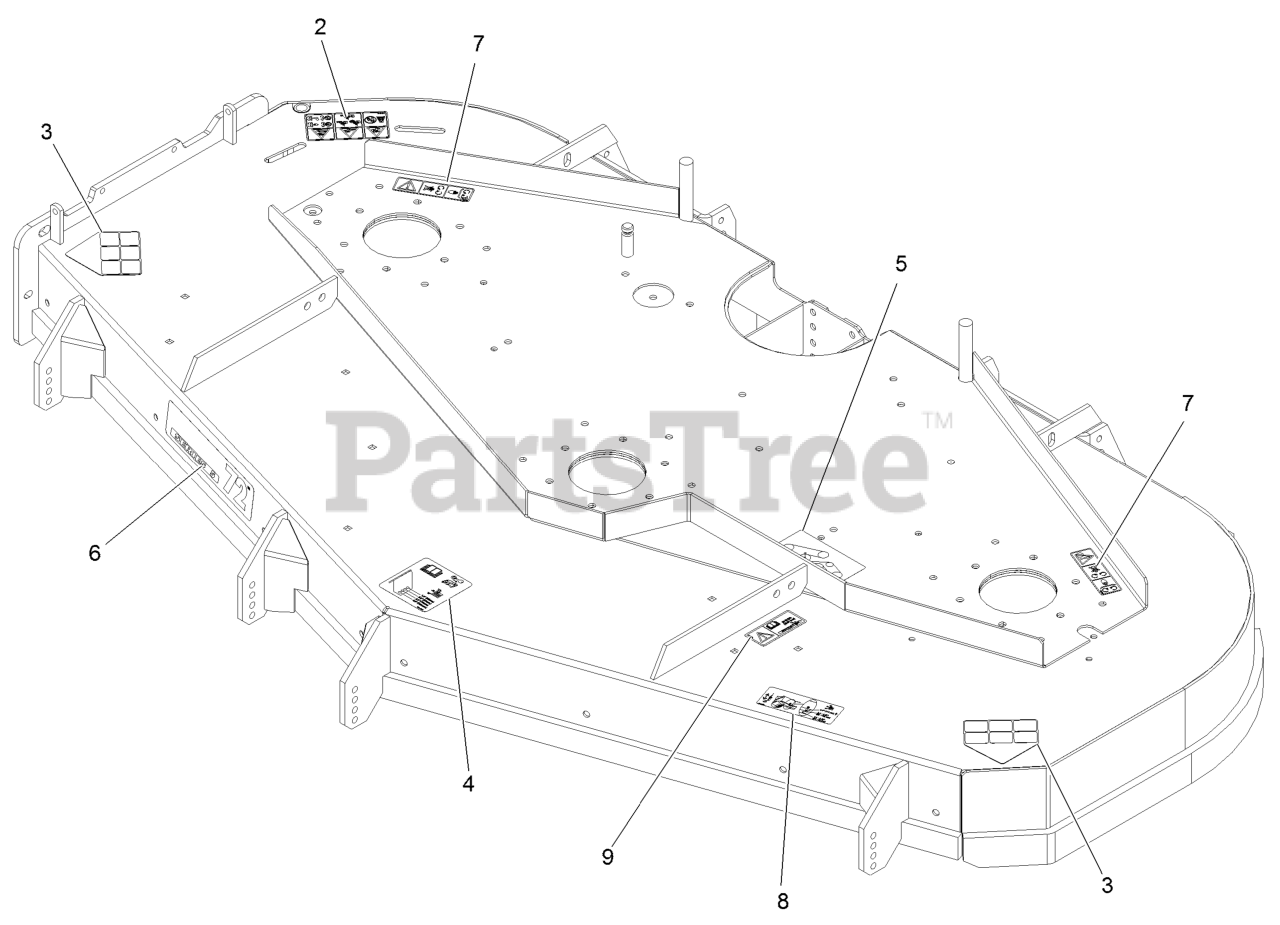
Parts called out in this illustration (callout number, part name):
2	DECAL-DANGER
3	DECAL-DANGER
4	DECAL-HEIGHT OF CUT
5	DECAL-BELT ROUTING
6	DECAL, SERIES 5 - 72
7	DECAL-COVER, MISSING
8	DECAL-BAFFLE ADJ
9	DECAL-BOLT TORQUE
